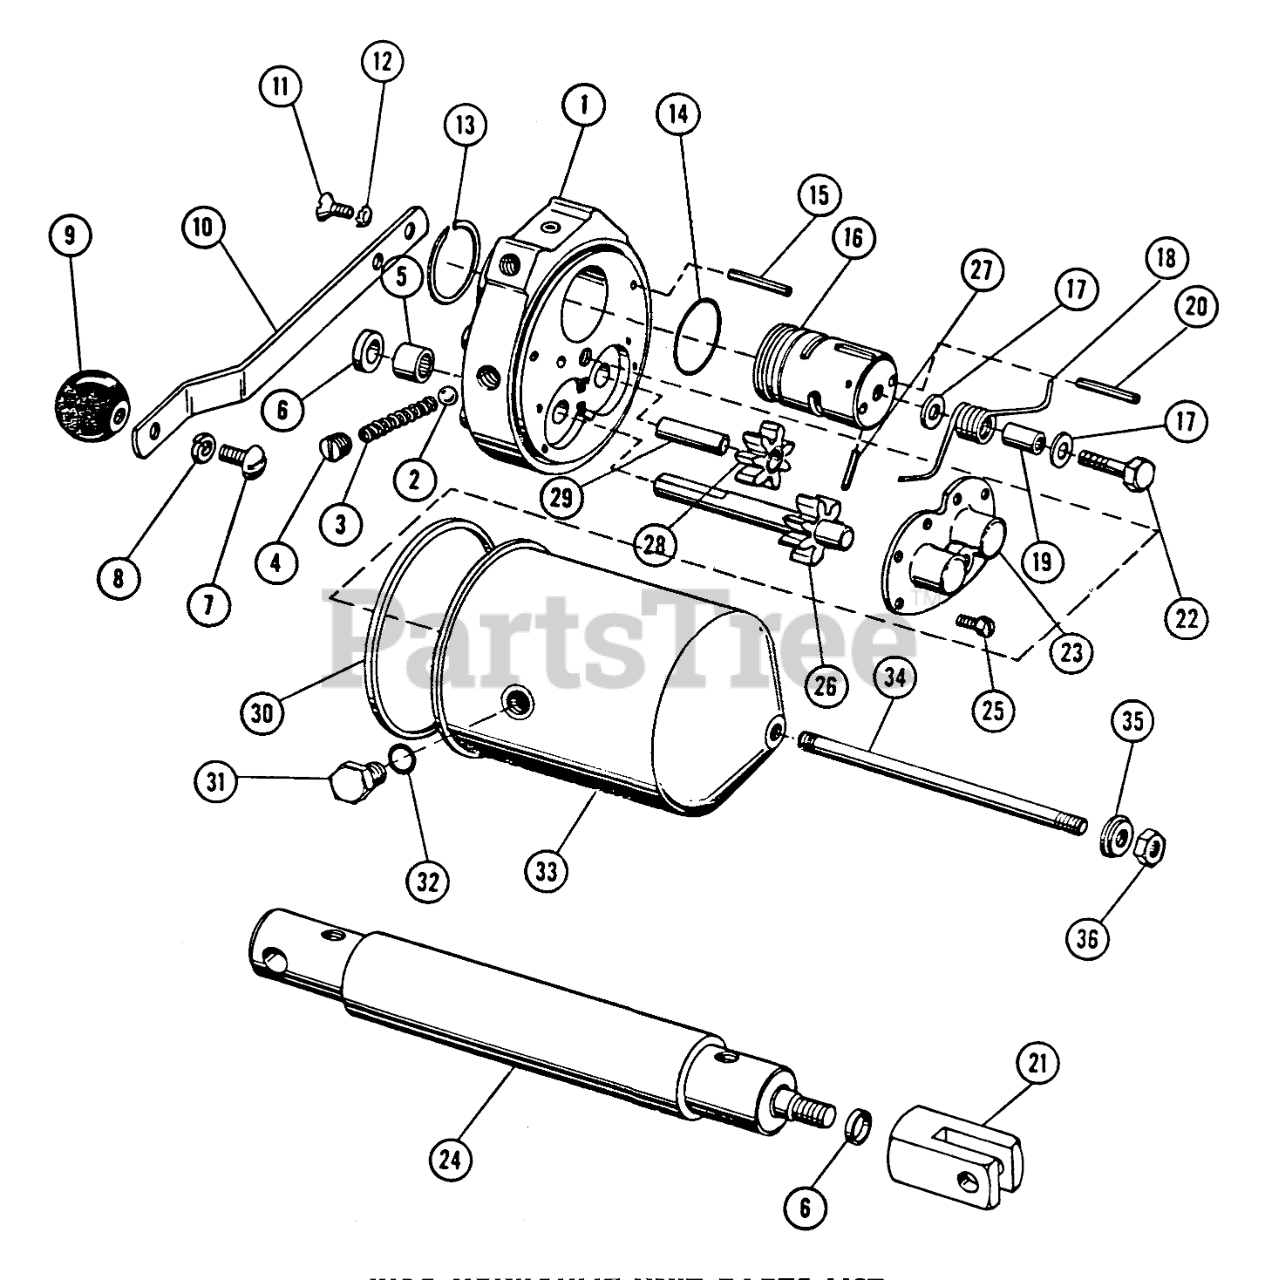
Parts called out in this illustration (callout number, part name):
1	Body
2	Ball
3	Spring
4	Plug
7	Screw 1/8-16 x 3/4
8	Lockwasher
10	Handle
11	Screw 1/4-20 x 3/8
12	Lockwasher
13	Snap Ring
14	O Ring
15	ROLL PIN
16	Spool Valve
17	Washer
19	Spring Sleeve
20	Roll Pin 5/32 x 1/4
21	Clevis
22	Bolt-Hex 5/16-18 x 1/8 Nylok
23	Cover
24	Cylinder Ass-y
25	Screw-Fill. Hd. 10-32 x 7/16 Sems
26	Drive Shaft Ass-y
27	Roll Pin 5/12 x 7/8
28	Gear Bearing Ass-y
29	Idler Shaft
30	Gasket
31	Bolt-Hex 1/2-20 x 1/2
33	Reservoir
34	Stud
36	3/8-16 Jam Nut
